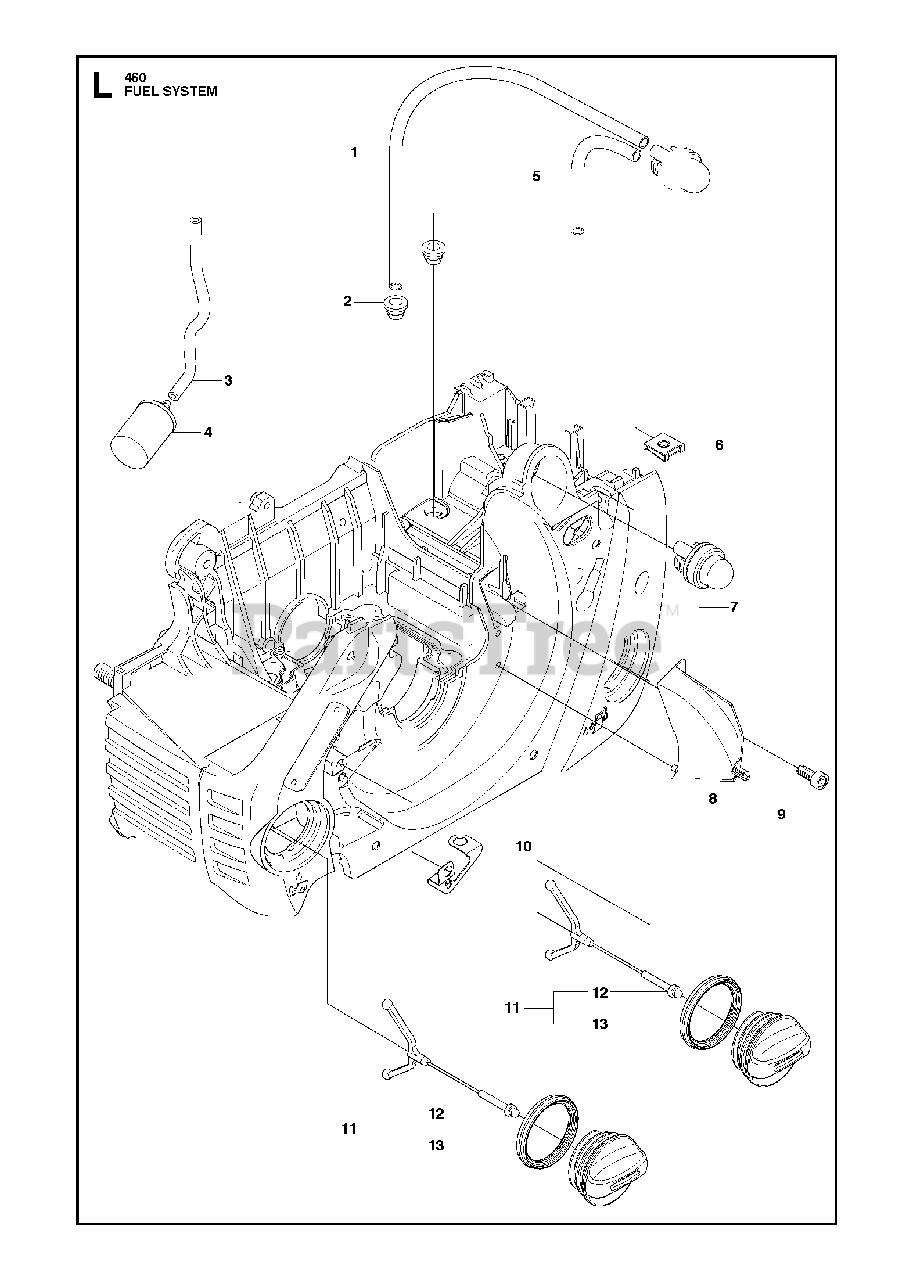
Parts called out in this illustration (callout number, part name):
2	FUEL TANK BUSHING
3	FUEL HOSE
4	FUEL FILTER
5	FUEL HOSE/38MM
7	AIR PURGE BUBBLE
10	SWITCH PLATE
11	TANK CAP
12	TANK LOCK
13	SEALING
